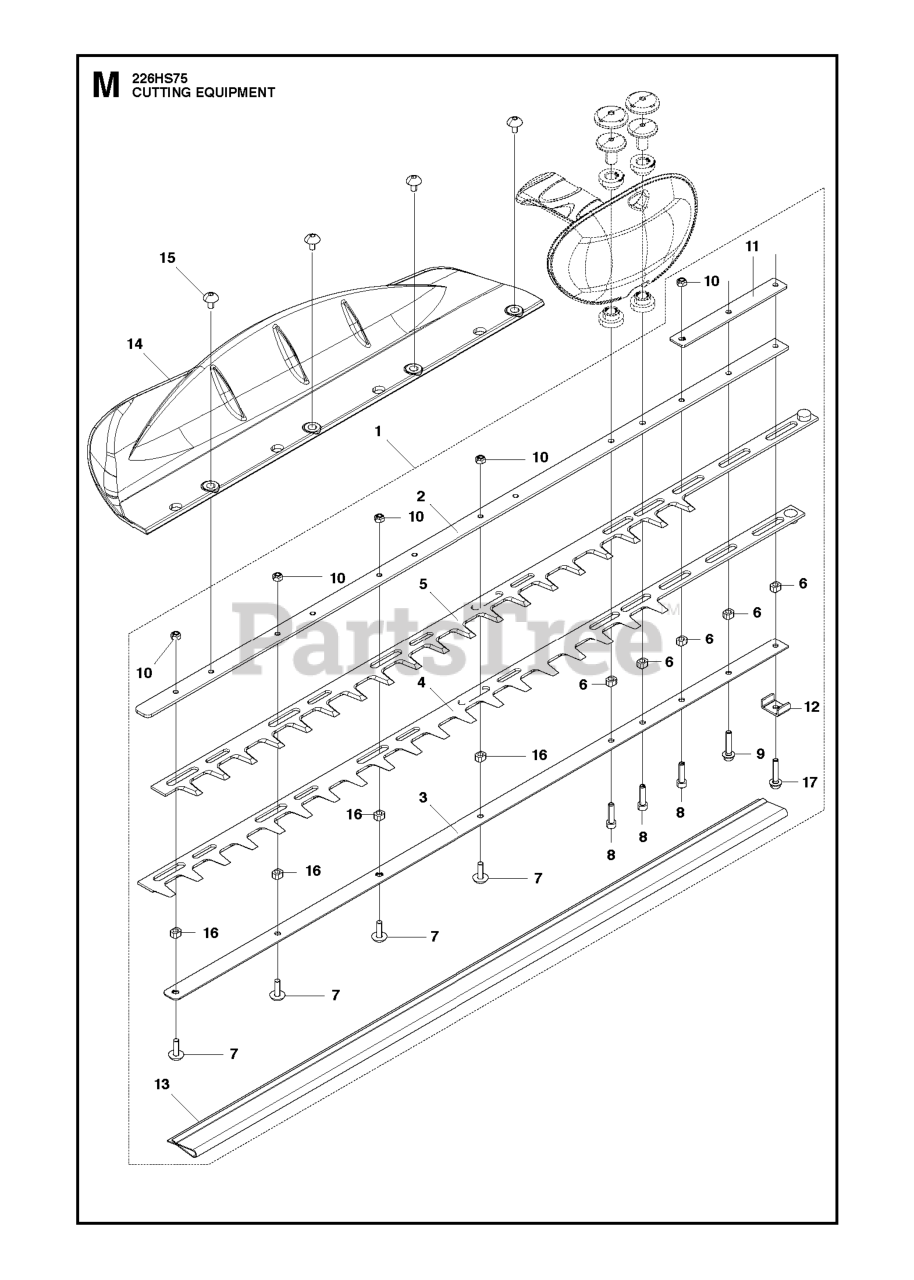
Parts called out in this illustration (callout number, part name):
2	PLATE,UPPER
3	PLATE,LOWER
4	BLADE,LOWER
5	BLADE,UPPER
8	BOLT
9	BOLT TORX M5XL35
10	PIPE,SHAFT-G
13	COVER, BLADE
